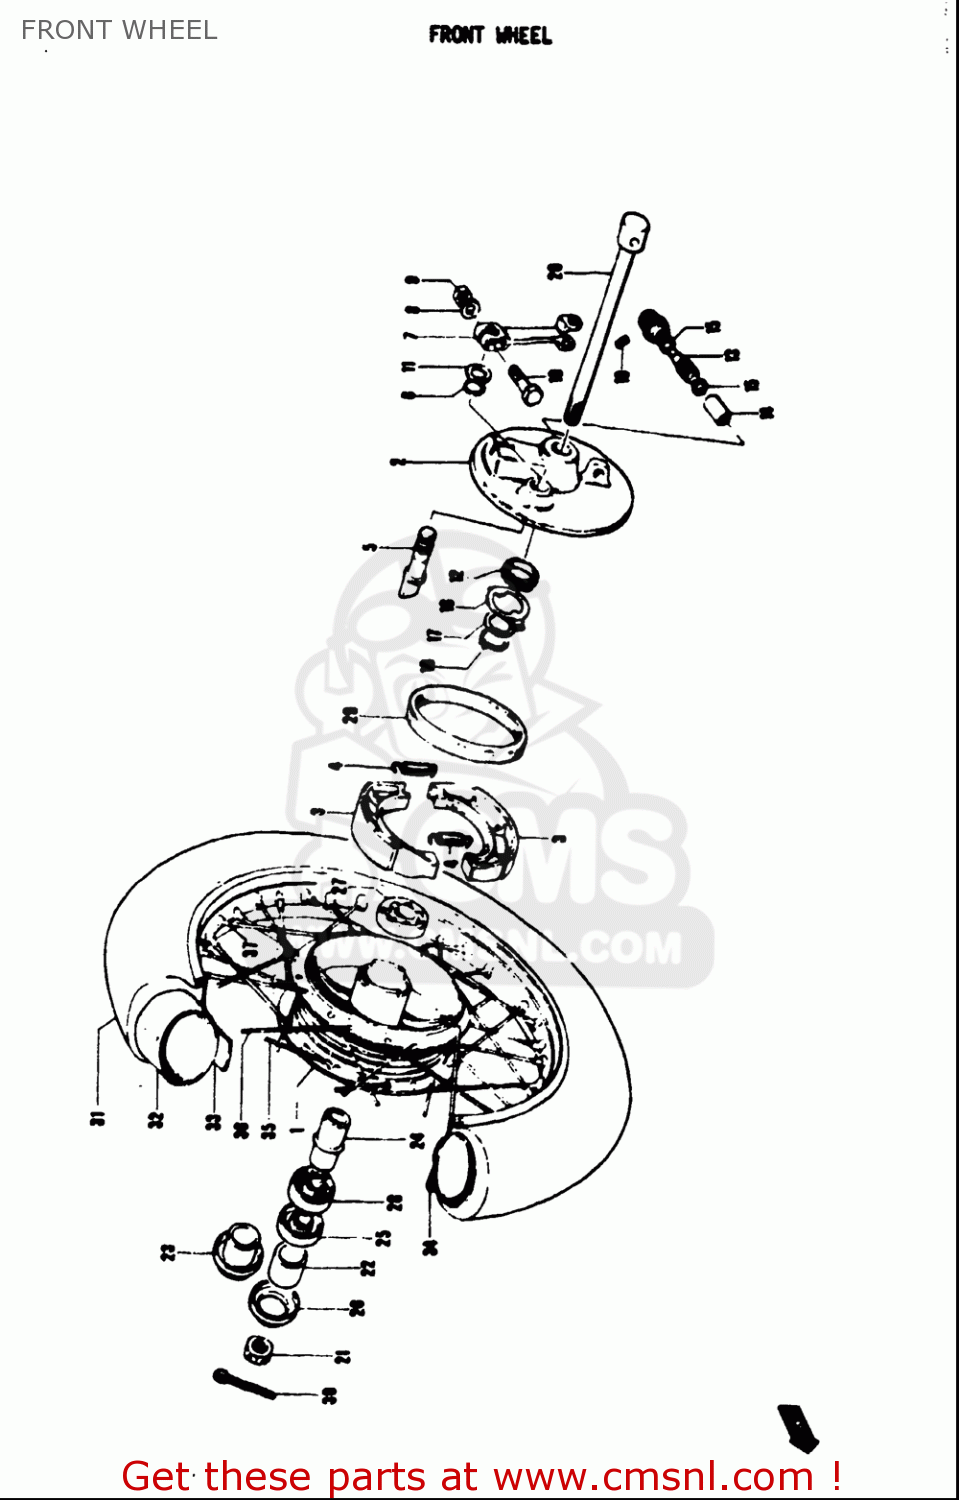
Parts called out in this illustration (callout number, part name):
3	SHOE & SPRING SET,BRAKE (NAS)
4	SPRING(L:35.8)
5	CAM,FR BRAKE
6	O RING(D:2.5,ID:11.4)
7	LEVER,FR BRAKE CAM
8	WASHER
9	NUT
10	BOLT(6X31)
11	WASHER(12.5X20X1)
12	GEAR,SPEEDOMETER(NT:24)
15	WASHER(5.1X9X0.4)
17	WASHER(16X22X1)
18	SCREW
19	CIRCLIP
20	AXLE,FR
21	NUT
22	SPACER(10X15X12.4)
23	SPACER,FR AXLE,R
25	SEAL,OIL(15X31X5)
27	BEARING
28	BEARING
29	SEAL,OIL(43X58X7)
30	COTTER PIN
31	TIRE,RR(2.25-17-4PR NR7/B)
33	PROTECTOR,WHL INR TUBE
34	SPOKE SET,FR
